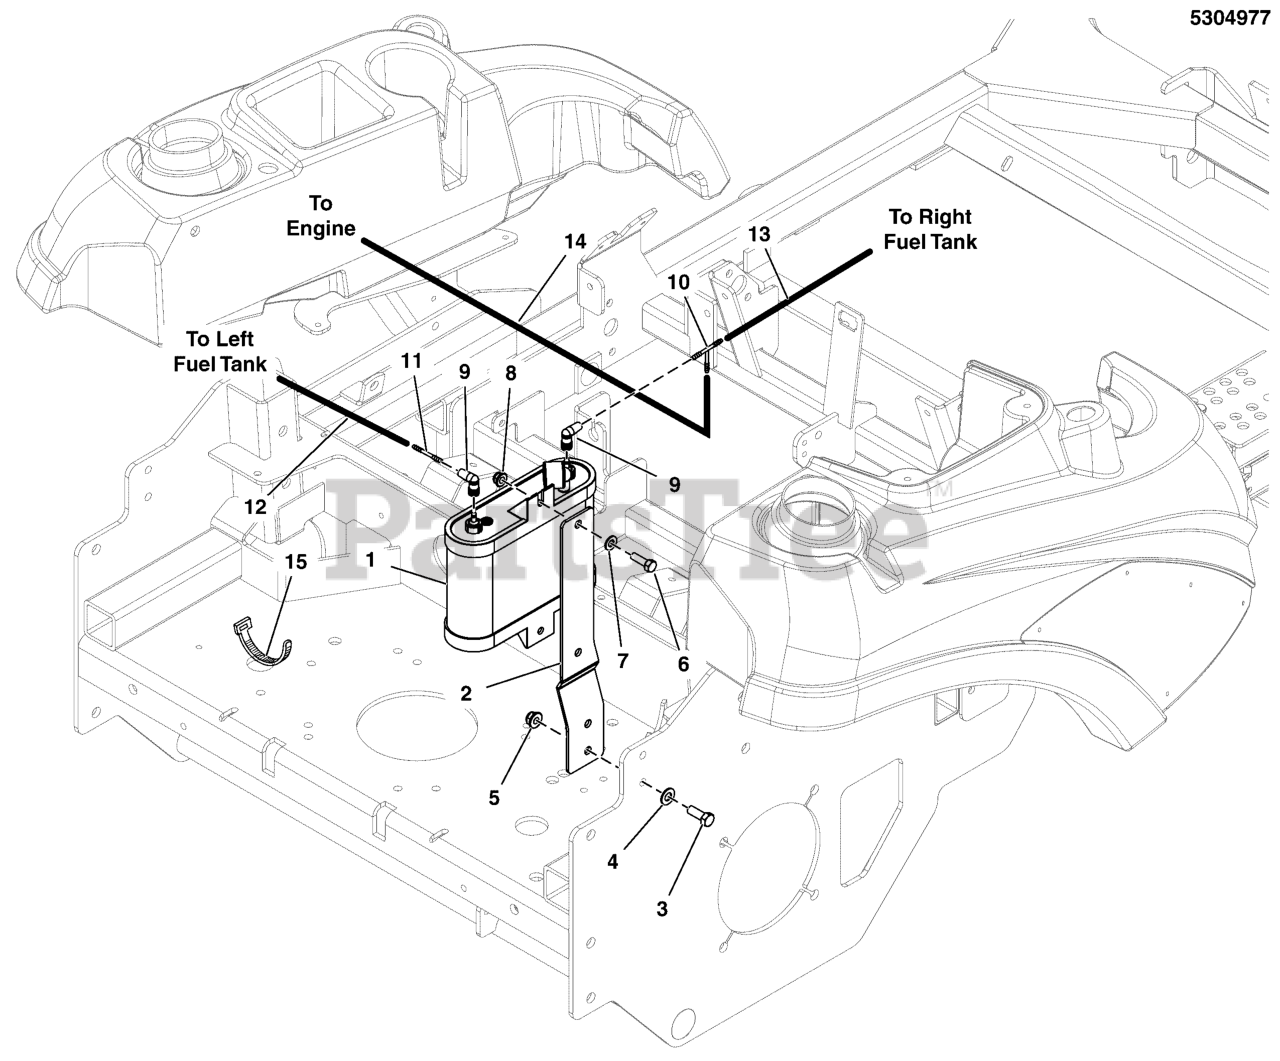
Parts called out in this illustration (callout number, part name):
1	CARBON CANISTER, 1 LITER, 12.8 GAL CAP
2	PLATE, EVAP CAN MNT - BLK
3	BOLT, 3/8-16 X 1" GD5 CZ
4	WASHER, 3/8 SAE
5	NUT, 3/8 - 16 HEX NYLOCK FLANGE
6	BOLT, 5/16-18 X 1" GRD5 YZ
7	WASHER, 5/16" SAE
8	NUT, 5/16-18 HEX NYLOCK FLANGE NUT
9	FITTING, 90 DEG, 3/16X3/16, SANTOPRENE
10	FITTING, 3/16" TEE, BARB TYPE, HDPE
11	FITTING, STRAIGHT, 3/16X3/16, PLASTIC
12	HOSE, VAPOR, 5MM ID, 20.00 LG
13	HOSE-VAPOR
14	HOSE, VAPOR, 5MM ID, 61.00 LG
15	TIE, SELF-LOCKING, 12"
